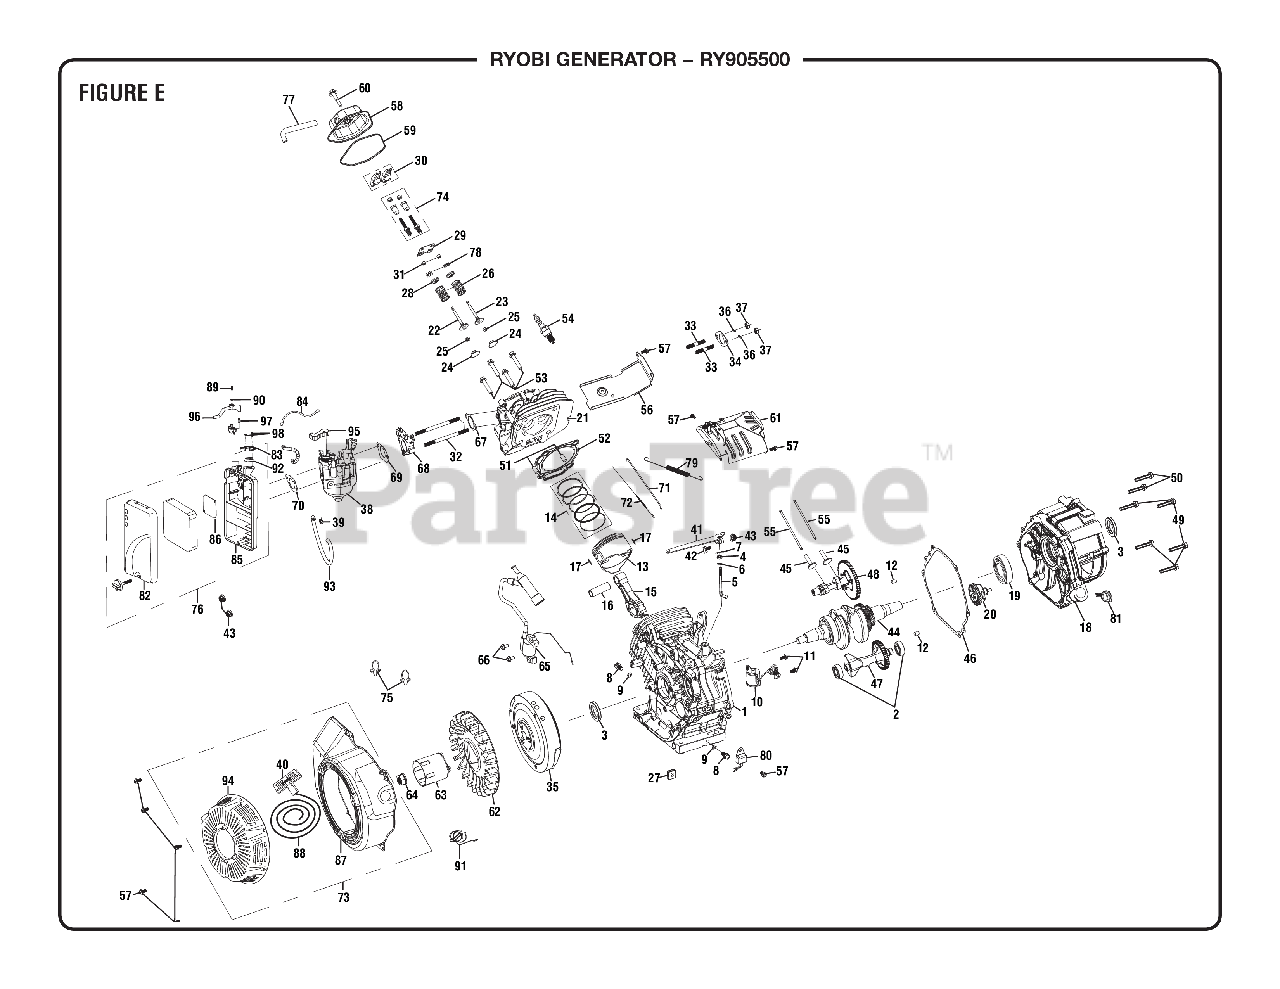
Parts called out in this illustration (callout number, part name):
1	Crankcase
2	Ball Bearing
3	Oil Seal
4	Governor Arm Shaft Seal
5	Governor Arm Shaft
6	Governor Arm Shaft Washer
7	Lock Pin
8	Drain Plug Bolt.
9	Drain Plug Washer
10	Oil Level Switch Assembly
11	Bolt (M6 x 16 mm)
12	Casecover Dowel Pin
14	Piston Scraper Ring Set
15	Connecting Rod Assembly
16	Piston Pin
17	Piston Clip
18	Crankcase Cover Assembly
19	Ball Bearing
20	Governor Assembly
21	Cylinder Head
22	Intake Valve
23	Exhaust Valve
24	Intake Valve Returner
25	Oil Seal Valve
26	Valve Spring
27	Starter Assembly Rubber
28	Exhaust Valve Spring Seat
29	Push Rod Guide Plate
30	Rocker Assembly
32	Stud Bolt
33	Stud Bolt
34	Exhaust Packing
35	Flywheel Assembly
36	Spring Washer
37	Hex Nut (M8)
38	Carburetor Assembly
39	Fuel Line Clip
41	Governor Arm
42	Governor Arm Bolt
43	Hex Nut (M6)
44	Crankshaft Assembly
45	Valve Lifter
46	Casecover Package
47	Balancing Shaft
48	Camshaft Assembly
49	Bolt (M8 x 35 mm)
50	Bolt (M8 x 40 mm)
51	Dowel Pin
52	Cylinder Head Gasket
53	Bolt (M10 x 80 mm)
54	Spark Pulg
55	Push Rod.
57	Bolt (M6 x 12 mm)
58	Cylinder Head Cover Comp
59	Headcover Packing
60	Lock Bolt
61	Upper Shroud Assembly
62	Recoil Starter Fan
63	Starter Pulley
64	Hex Nut (M5)
65	Ignition Coil Assembly
66	Bolt (M6 x 25 mm)
67	Intake Packing
68	Carburetor Insulator
69	Carburetor Packing
70	Carburetor Spacer
71	Governor Rod
72	Throttle Return Spring
73	Recoil Starter Assembly
74	Rocker Arm Adujuster
76	Air Cleaner Assembly
77	Breather Tube
78	Locking Flaps
79	Governor Spring
80	Amplifier
81	Dipstick
82	Air Cleaner Cover
83	Enginge Stop Switch
84	Flameout Wire
85	Air Cleaner Bottom Cover
86	Element Bracket
87	Recoil Starter Assembly
89	Screw (M4 x 10 mm, Phillips Pan Hd.)
91	Switch Assembly
92	Engine Switch Bracket
93	Fuel Hose (330 mm)
94	Recoil cover
95	Choke Lever (Grey)
96	Control Lever (Grey)
97	Screw (M6 x 10 mm, Pan Hd.)
98	Screw (St 2.9 x 16 mm, Pan Hd)
